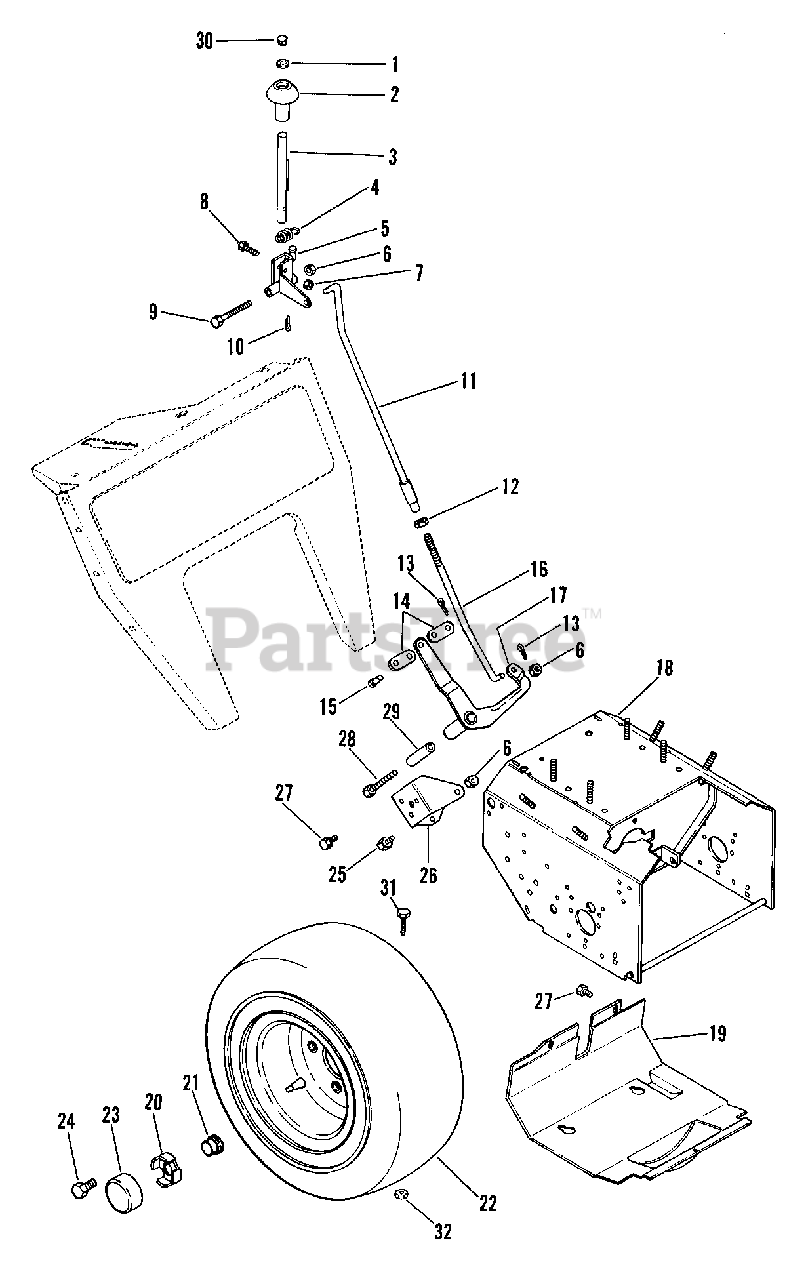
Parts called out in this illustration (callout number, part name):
1	RG-RTNG-EXT .500X.015
3	ROD
4	SG-TENS .055X.33X1.31 WLD 7
6	NUT-LK .312-18 GR A PL
7	NUT-LK-CTR .250-20 PL
8	BLT-HEX .25-20X1.00 GR2
9	BLT-HEX .31-18X2.50 PL GR2
10	PIN-COTR .12X.75 PL
11	UPPER SHIFT ROD
12	NUT-HEX .312-24 PL
13	PIN-COTR .09X.75 PL
14	SHIFT LINK
15	CLEVIS PIN
16	LOWER SHIFT ROD
17	LEVER - SHIFT ARM
18	TRACTOR FRAME ST824-ST1032
18	TRACTOR FRAME
18	FRAME
18	TRACTOR FRAME ST1236
19	BOTTOM COVER
20	SPINDLE CUP
21	PUSHNUT
21	PIN-COTR .12 X 1.25 PL
22	TUBE
22	WHL 6 IN O.D.
22	TIRE 4.10/3.50X6
22	T/WHL ASSY
22	WHL
22	TIRE
22	T/WHL ASSY 4.80/4.00 X 8
22	TIRE 16X6.50-8 2 PLY
22	T/WHL ASSY 6.50-8 X 16
22	TIRE 4.80-8 NHS
22	T/WHL ASSY 4.80-8
22	TIRE 16X6.50-8 SNO-HOG TREAD
22	T/WHL ASSY 16X6.50-8 SNO-HOG
22	RIM/HUB ASSY 4.10/3.50X6
22	T/WHL ASSY 13 X5.0-6 SNO HOG
23	HUB CAP
23	HOLE PLUG
24	SCR-TAP .500-20X.62 HH PL
25	BLT-HEX .31-18X.50 PL GR2
26	BRACKET SHIFT LEVER
27	SCR-TAP .312-18X.50 HWH PL TR
28	BLT-HEX .31-18X3.00 PL GR2
29	SPACER .5 X .33 X 2.4
30	HOLE PLUG
31	BLT-HEX .25-20X1.75 GR2
32	NUT-LK TOP .250-20 PL
